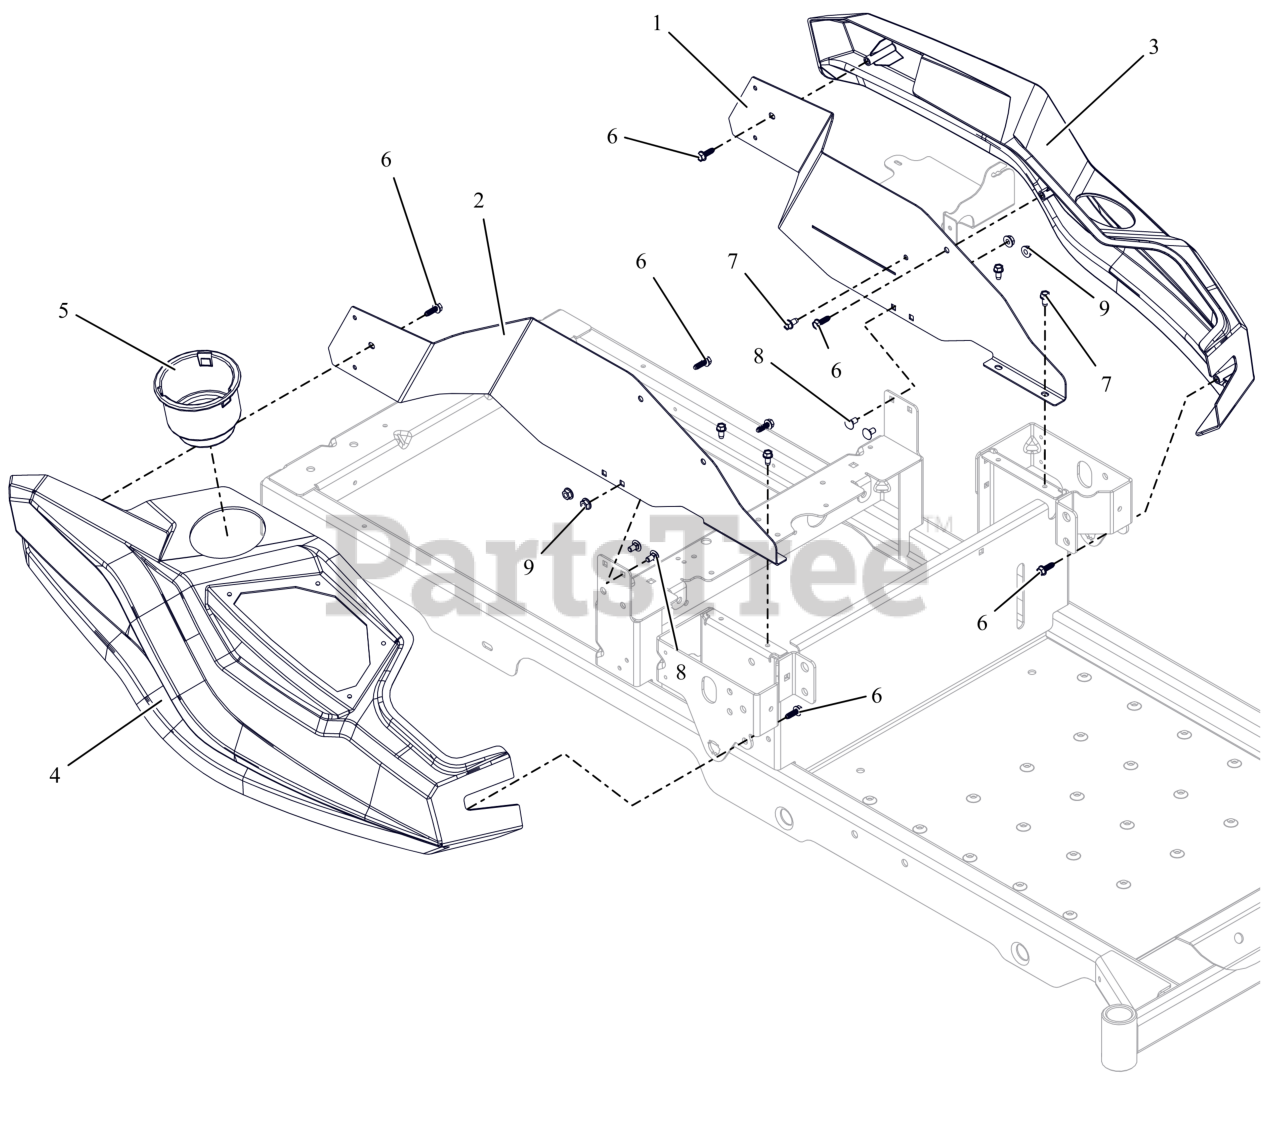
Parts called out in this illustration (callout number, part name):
1	BRKT, FENDER MOUNTING LH (ORANGE)
2	BRKT, FENDER MOUNTING RH (ORANGE)
3	KIT-FENDER WITH DECAL
4	FENDER, RH - ZOOM
5	CUPHOLDER, SNAP-IN 3.75OD
6	SCR, PLASTITE .25-10X.75 ZCC
7	SCR-TAP .25-20X.50 HWH ZCC
8	BLT, RHSN .25-20X.500 G5 ZCC
9	NUT-LK-CTR-FLG .25-20 ZC120
